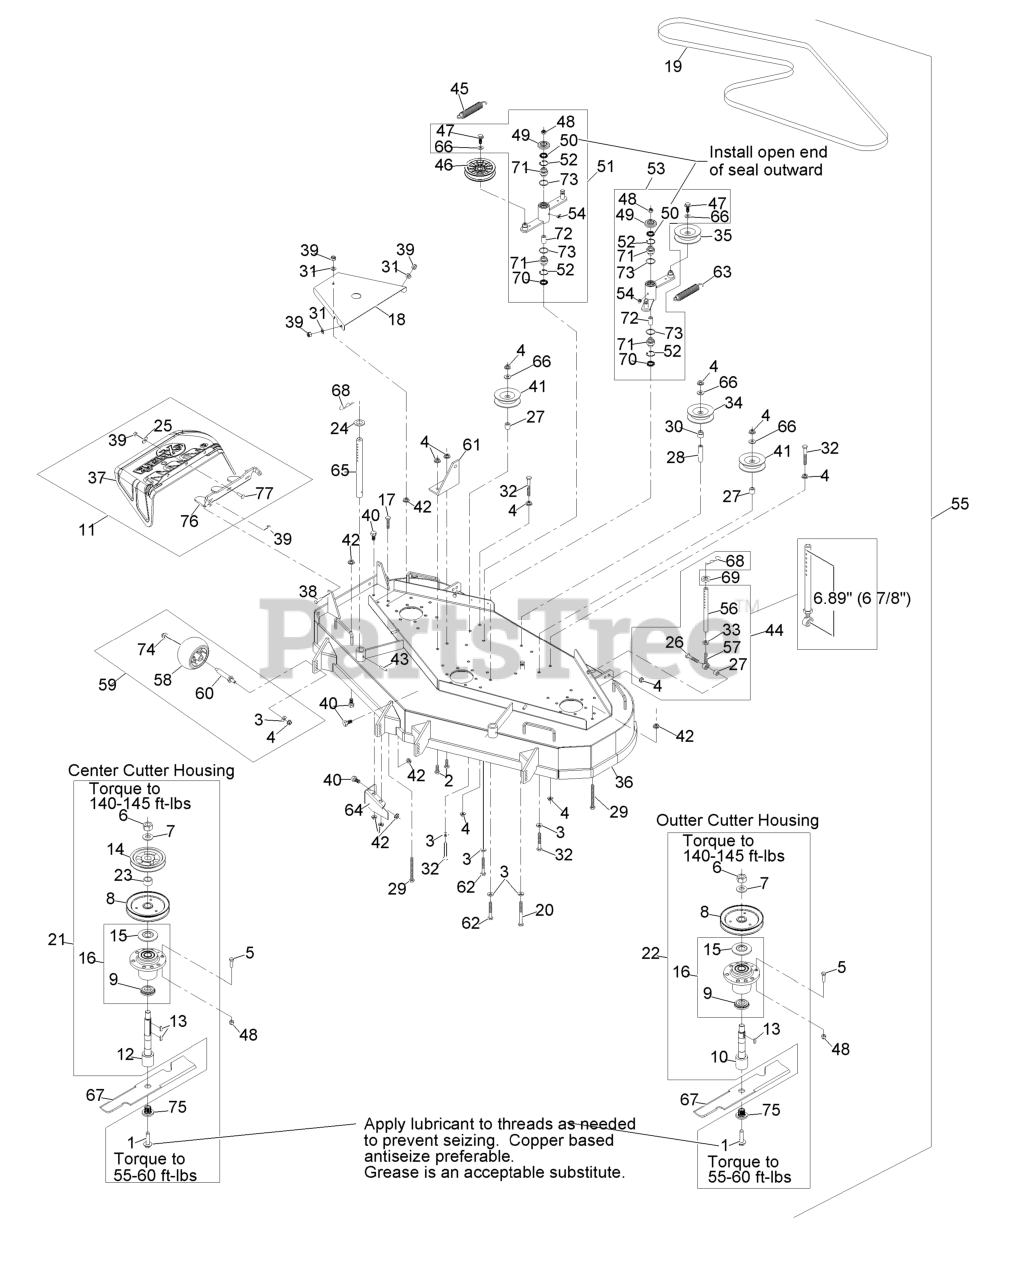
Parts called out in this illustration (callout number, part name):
1	SCREW,SEMS 1/2-20 X 2.19
2	SCREW-HH
3	WASHER-BELLEVILLE
4	NUT-HHF, WHIZ
5	SCREW-HH
8	SHEAVE,BLADE DRIVE 6.30
9	SPACER-GUARD, BOTTOM
10	KIT, SPLINED SPINDLE 103-
11	ASM,FMD DISCHARGE CHUTE
12	KIT, SPLINED SPINDLE 103-
14	SHEAVE,MOWER DRIVE
15	GUARD-BEARING, TOP
16	KIT, CUTTER HOUSING
17	SCREW-HH
18	SHIELD,BELT SIDE FMD524
19	BELT,BLADE DRIVE FMD524
20	SCREW-HH
21	ASM,CUTTER HSG FMD524 CTR
22	ASM, CUTTER HSG COMPLETE
23	SPACER,TUBE
24	SPACER-DECK SUPPORT
25	WASHER-FLAT
26	SCREW-HH
28	SPACER-ANCHOR, CLUTCH
29	BOLT,TAP HH
30	BUSHING,IDLER
31	WASHER-FLAT
32	BOLT-CARR
33	NUT-HJ
34	PULLEY-IDLER
35	PULLEY-IDLER
36	ASM, DECK W/ DECALS FMD52
37	CHUTE,DISCHARGE
38	SCREW-HH
39	NUT-LOCK, NI
40	SCREW-HH
41	IDLER,PULLEY
44	KIT,SUPPORT LINK W/PIN
45	SPRING-EXTENSION
46	PULLEY-IDLER, FLAT
47	SCREW-HHF
48	NUT-LOCK, NI
49	GUARD-TOP
50	SEAL-LIP, SINGLE
51	KIT, IDLER ARM W/BEARINGS
52	RING-SNAP
53	KIT, IDLER ARM W/BEARINGS
54	FITTING-GREASE, 90 DEG
55	Asm, Complete Deck
56	LINK,SUPPORT
57	BALLJOINT
58	ROLLER-SCALP, ANTI
61	BRACKET,SPRING ANCHOR
62	SCREW-HH
63	SPRING-EXTENSION
64	BAFFLE,DISCHARGE
65	ROD,DECK SUPPORT
66	WASHER-FLAT
68	PIN,HAIR COTTER
70	SEAL-LIP, DOUBLE
71	BEARING-SPHERICAL
72	BUSHING-LEVER, LIFT
74	Nut-Nyloc 3/8-16 Flg
75	BUSHING,SPLINED
76	BRACKET, DISCHARGE CHUTE
77	SCREW-CARR
